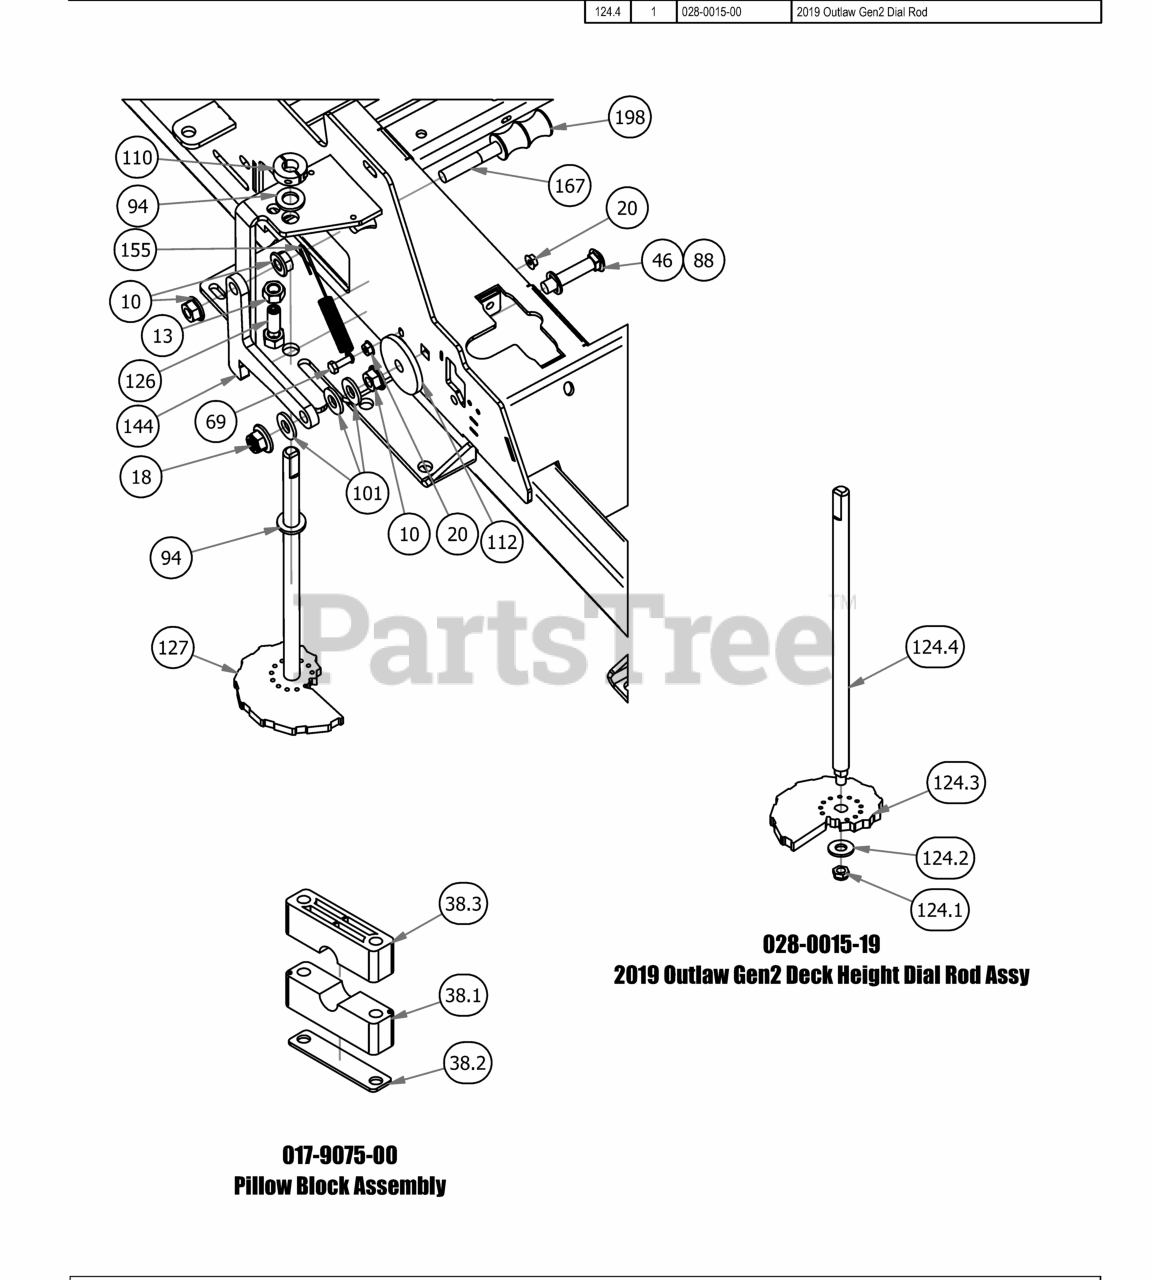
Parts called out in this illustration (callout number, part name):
10	1/2" Flange Nut
13	1/2" Hex Nut
18	1/2-13 NYLON INSERT FLANGE LOCKNUT ZINC
20	1/4-20 Hex Flange Nuts Zinc w/Serrations
38.1	Two Piece Pillow Block (Male)
38.2	Two Piece Pillow Block Strap
38.3	Two Piece Pillow Block (Female)
46	1/2 x 2-1/2 Carriage Bolt
69	1/4-20 x 1-1/4 GR 5 Hex Bolt
88	.517 Square Hole Round Washer
94	.635 ID X 1.120 OD X .140 THICK FLAT WASHER NYLON
101	.505 Nylon Spacer
110	5/8" Split Collar
112	MZ Deck Idler Spacer
124.1	3/8-24 Nylon Insert jam locknut
124.2	3/8" Flat Washer
124.3	2019 Deck Height Cam
124.4	2019 Outlaw Gen2 Dial Rod
126	Dial Rod Plunger
127	2019 Outlaw Gen2 Deck Height Dial Rod Assy
144	2019 Outlaw Deck Travel Lock
155	Brake Spring
167	Seat Bracket Pin
198	Travel Lock Rubber Grip
